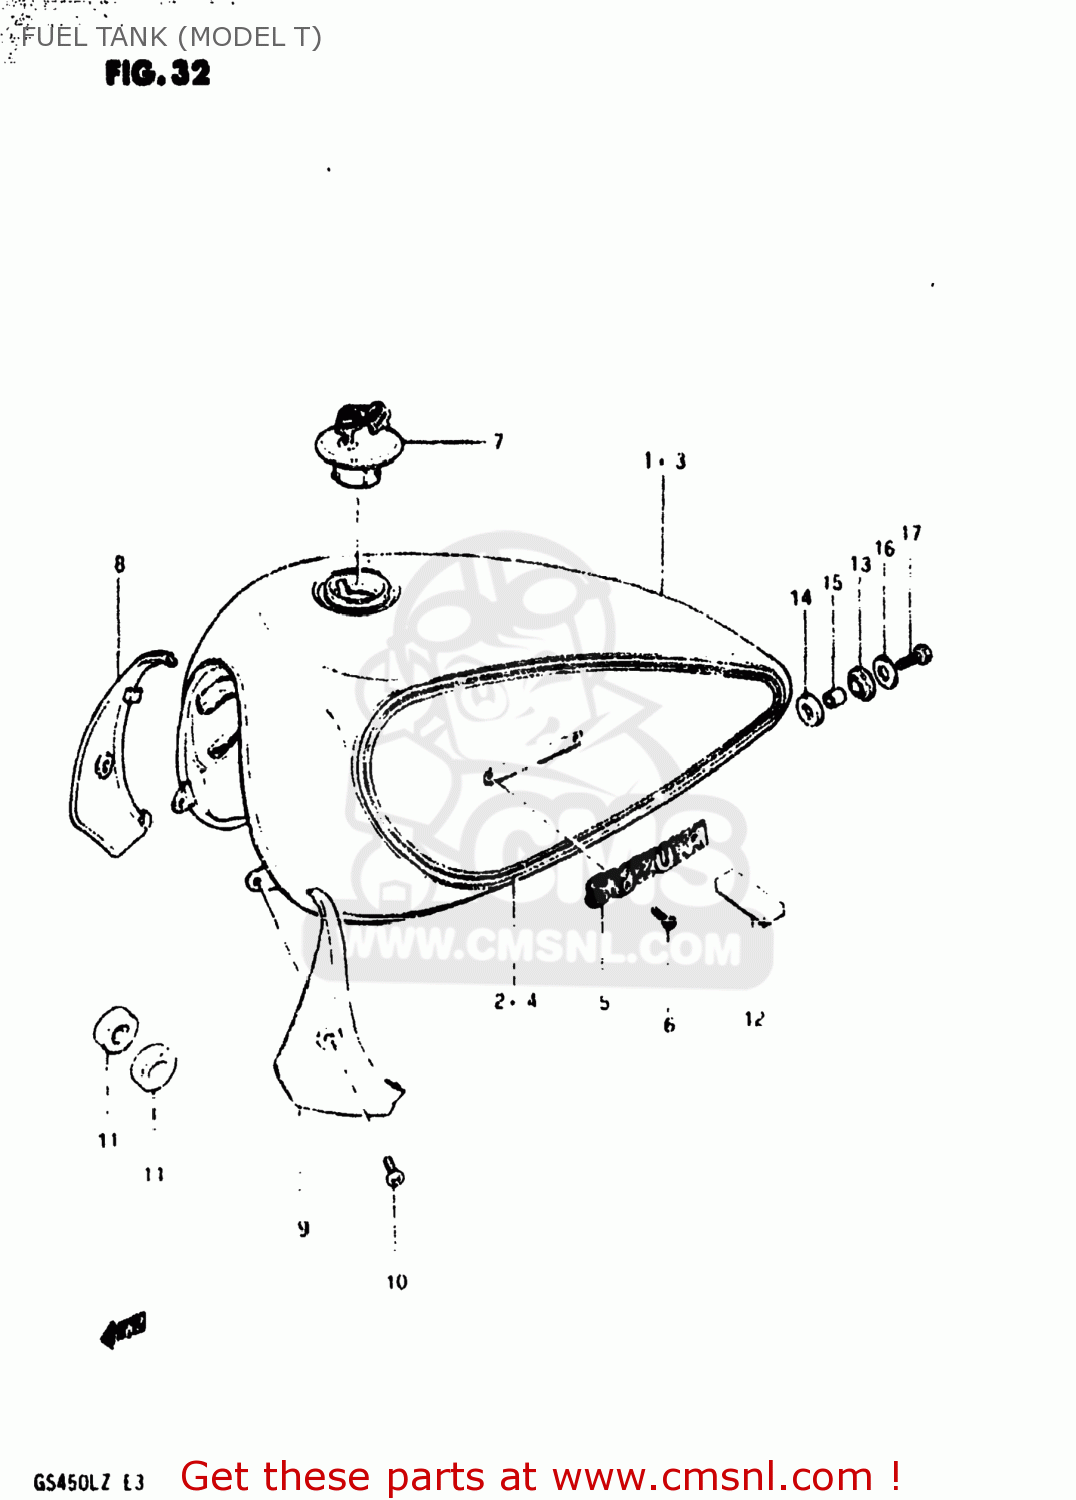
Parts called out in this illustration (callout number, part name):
1	TANK ASSEMBLY,FUEL
2	TAPE SET,FUEL TANK STRIPE
3	TANK ASSEMBLY,FUEL
4	TAPE SET,FUEL TANK
5	EMBLEM,FUEL TANK
6	SCREW 3X6
7	CAP SET,FUEL TANK
8	COVER,FUEL TANK
9	COVER,FUEL TANK
10	SCREW 6X12
11	CUSHION
12	CUSHION
13	CUSHION
14	CUSHION
15	SPACER(8.5X12X19)
16	WASHER (8.5X29X1.6)
17	BOLT (8X30)
